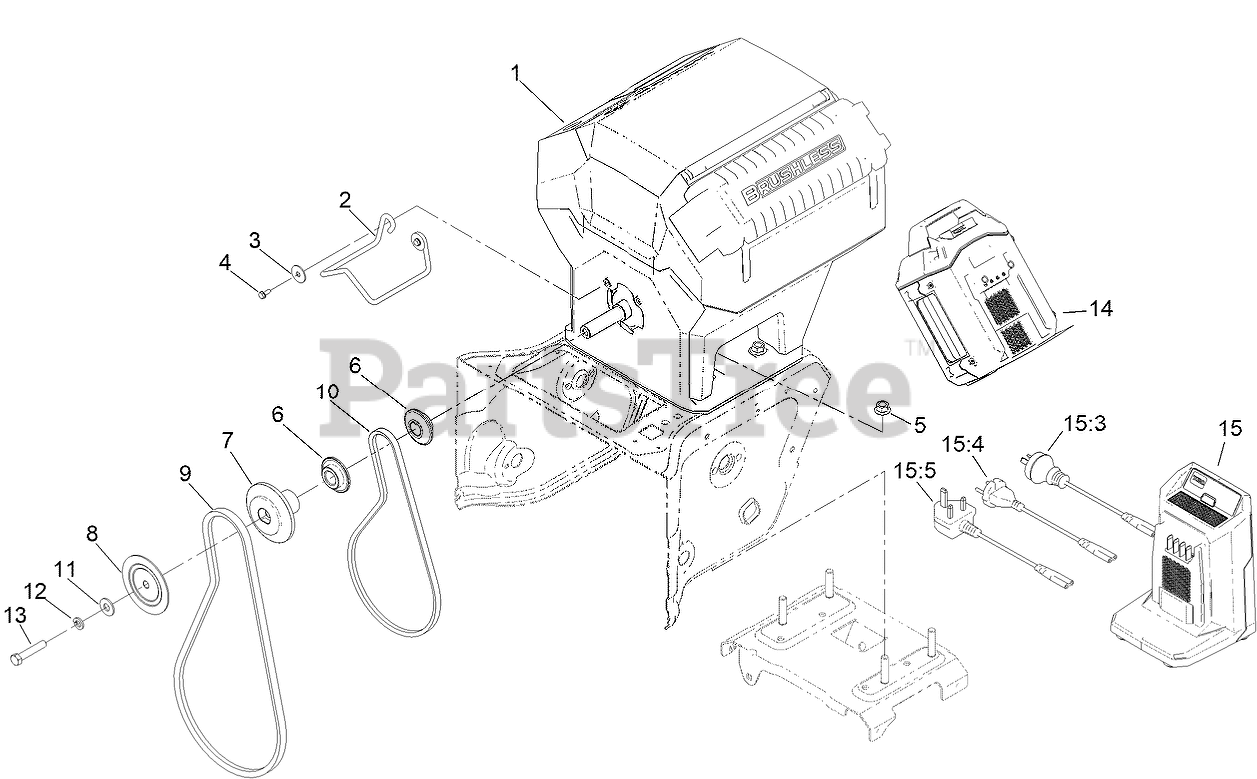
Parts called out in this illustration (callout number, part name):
1	POWERHEAD-60V
2	GUIDE-BELT
3	WASHER-FLAT
4	SCREW-HWH, THD ROLL
5	NUT-LOCK
6	PULLEY-ENGINE, TRACTION
7	PULLEY-AUGER, REAR
8	PULLEY-AUGER, FRONT
9	BELT-V
10	BELT-V
11	WASHER-PLAIN
12	WASHER-LOCK
13	SCREW-HH
14	60V 7.5AH BATTERY CE
15	CHARGER, RAPID 60V
15:3	CORD-CHARGER, AU/NZ
15:4	CORD-CHARGER, CE
15:5	CORD-CHARGER, UK
